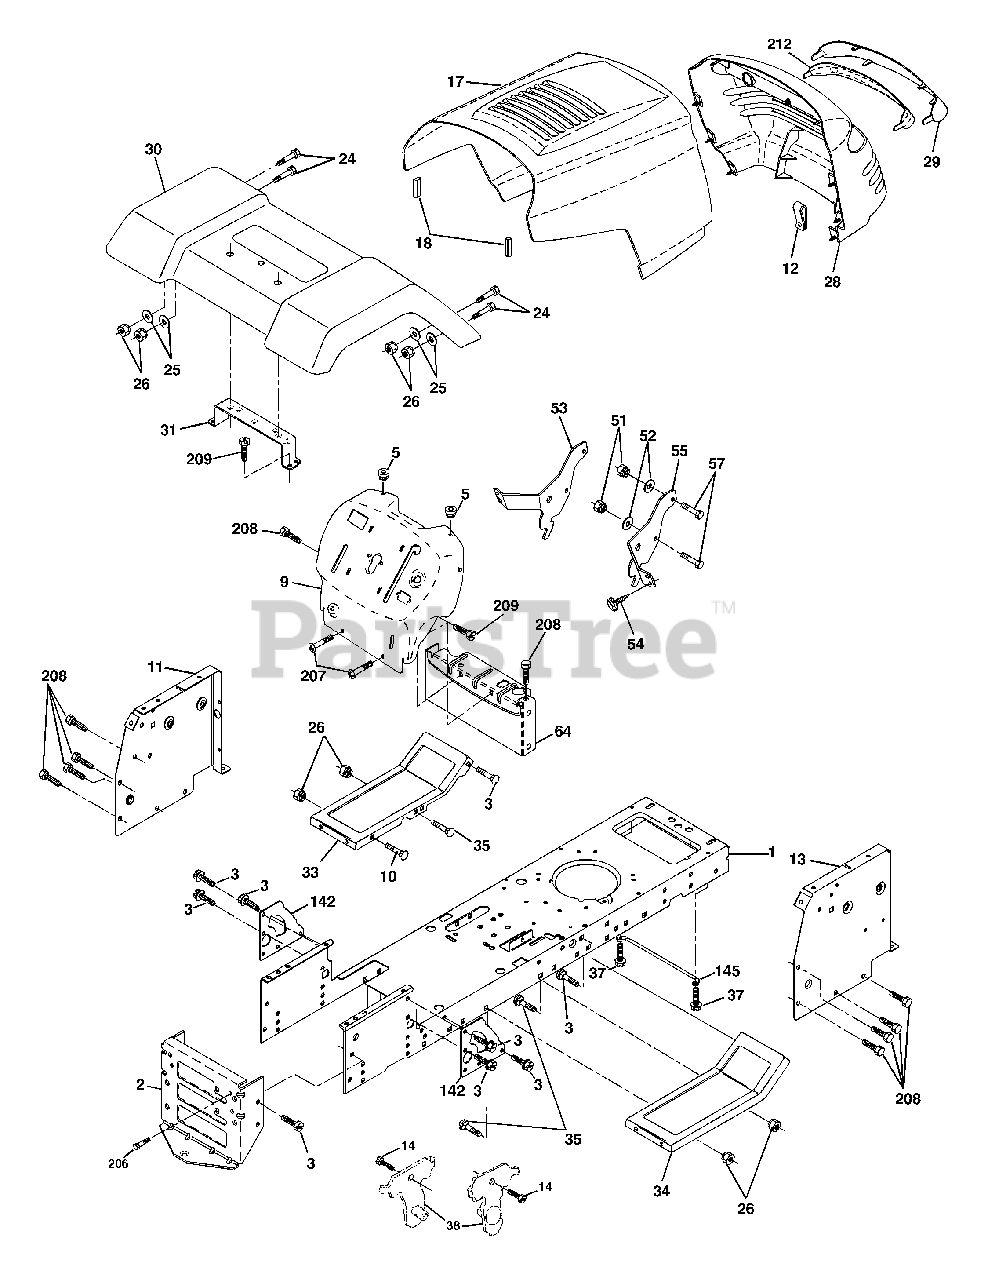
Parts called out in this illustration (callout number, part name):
1	Chassis
2	Drawbar
3	Screw 3/8-16 x 3/4
5	Bumper Hood/Dash
10	Bolt Rd Hd Sqnk. 3/8-16 Unc x 1
11	Panel Asm. Dash Lh
12	Clip Tinnerman Grile P/L
13	Panel Dash Rh
14	Screw Thdrol 3/8-16 x 1/2
17	Hood
18	Bumper Hood
24	Bolt Fin Hex 3/8-16 Unc x 1 Gr. 5
25	Washer 13/32 x 13/16 x 12 Ga.
26	Nut Lock Hex w/Insert 3/8-16 UNC
28	Grill/Lens Asm
29	Lens Grille Private label
30	Fender Asm
31	Bracket Fender
33	Footrest LH
34	Footrest RH
35	Bolt Rd Hd Sht. Sqnk. 3/8-16 x 3/4
37	Screw Thdrol 5/16-18 x 1/2 Tyt
38	Bracket Asm. Pivot Mower Rear
51	Nut Lock Hex W/Ins. 1/4-20
52	Washer 9/32 x 7/8 x 16 Ga.
53	Bracket Grille LH
54	Screw Hex Wshd 8-18 x 7/8
55	Bracket, Grille RH
57	Bolt Fin Hex 1/4-20 x .75
64	Dash Lower
142	Plate Reinforcement
145	Rod Pivot Chassis/Hood
206	Bolt shoulder 5/16-18
207	Screw Thdrol 5/16-18 x 1/2
208	Screw Thdrol 3/8-16 x 1/2
209	Screw 3/8-16 x 3/4
212	Insert Lens Reflector
